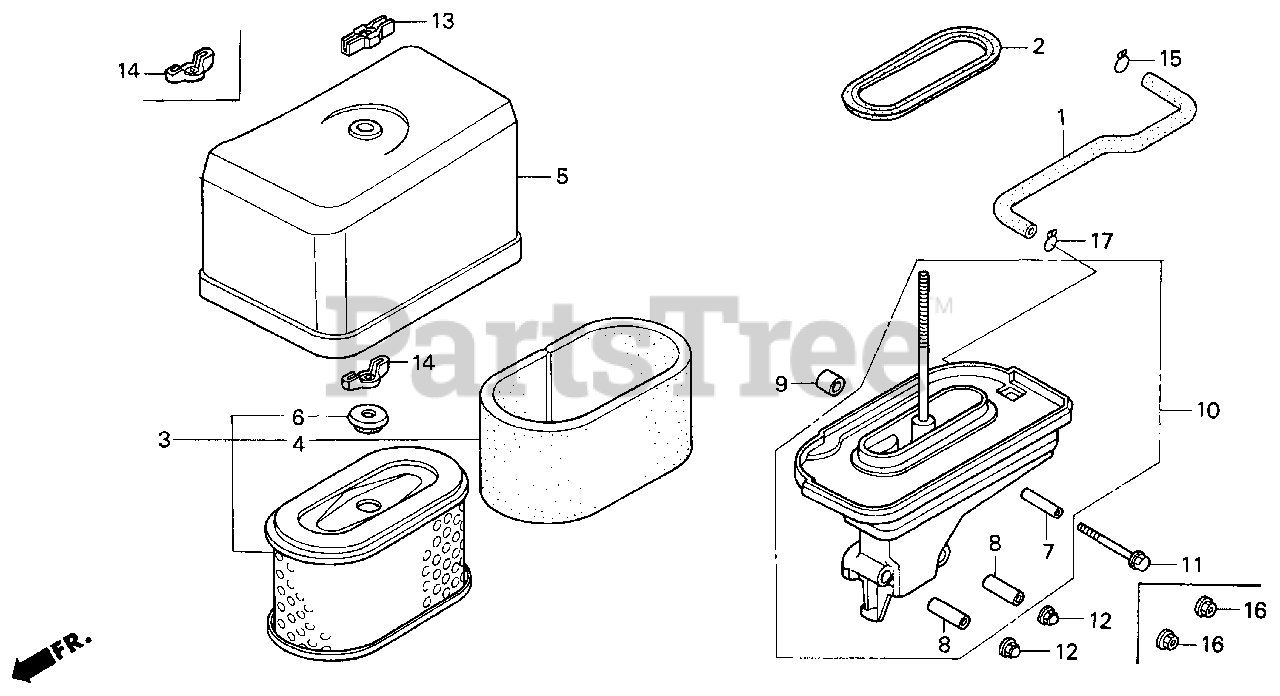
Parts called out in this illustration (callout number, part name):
1	TUBE, BREATHER
2	GASKET, ELBOW
3	ELEMENT, AIR CLEANER (METAL BASE)
4	FILTER (OUTER)
5	COVER, AIR CLEANER (DUAL)
6	GROMMET, AIR CLEANER
7	COLLAR, AIR CLEANER
8	COLLAR, AIR CLEANER
9	SPACER, AIR CLEANER ELBOW
10	ELBOW, AIR CLEANER
11	BOLT, FLANGE (6X50)
12	NUT, CAP (6MM)
13	WINGNUT (6MM)
14	WINGNUT, TOOL BOX SETTING
15	CLIP, TUBE
16	NUT, FLANGE (6MM)
17	CLIP, TUBE (C11)
